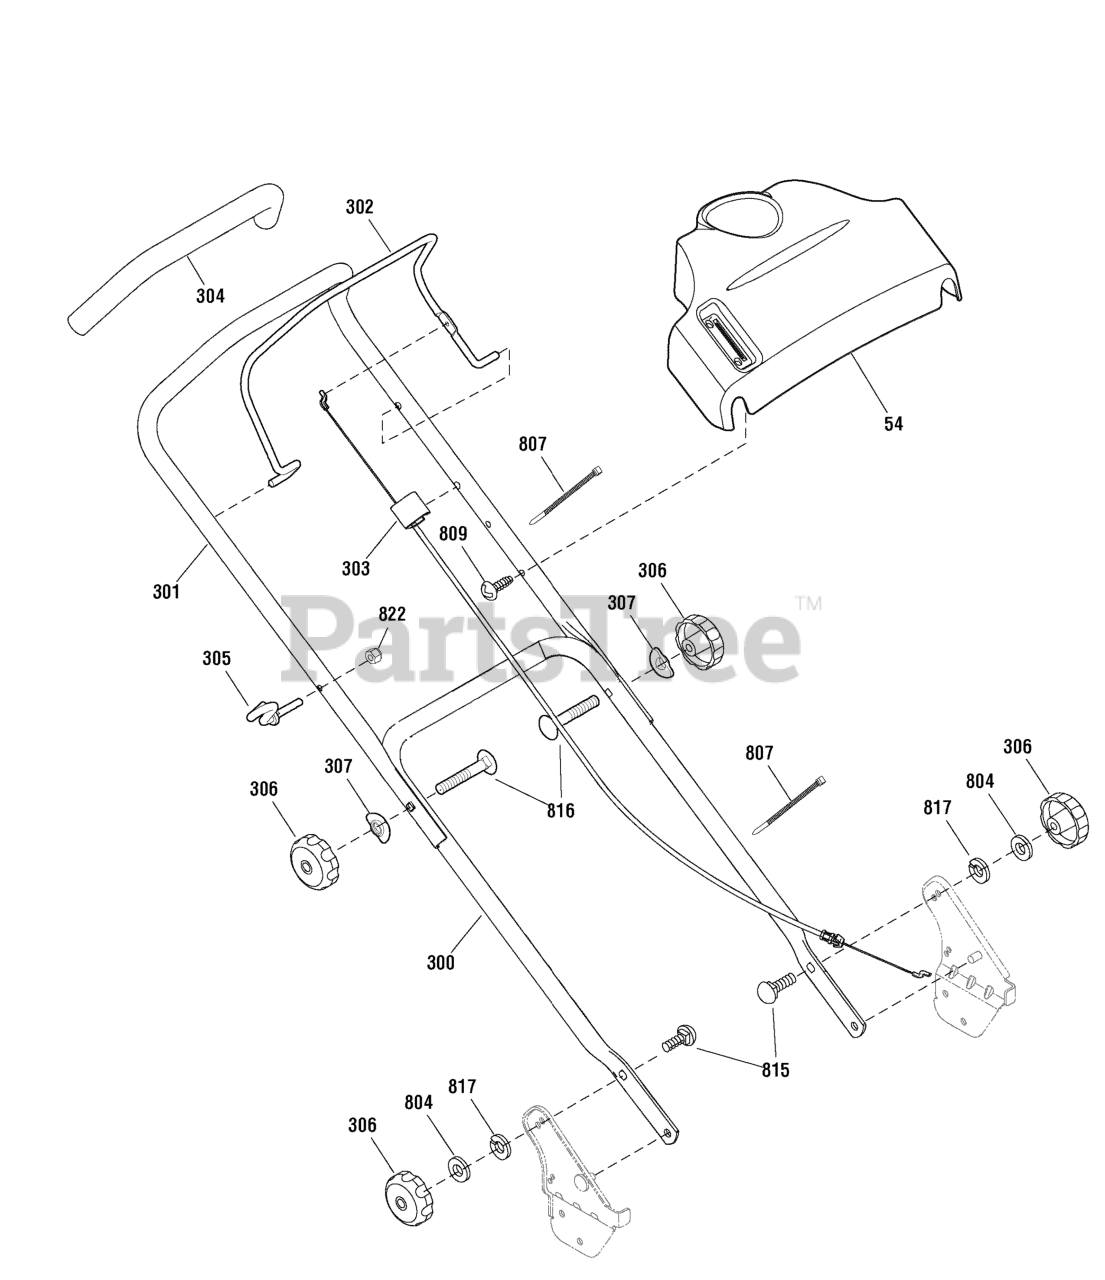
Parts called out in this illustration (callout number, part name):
54	CONTROL PANEL
300	HANDLE, Lower
301	HANDLE, Upper
302	LEVER, Engine Stop
303	CABLE, Engine Stop
304	TUBING, Foam
305	GUIDE, Rope
306	KNOB, Adjuster
307	WASHER, Formed
804	WASHER, 5/8
807	CABLE TIE
809	SCREW, Self Tap, #10-16 x 1/2
815	BOLT, Carriage, 5/16-18 x 1-1/8
816	BOLT, Carriage, 5/16-18 x 2
817	Washer, Lock
822	NUT, Hex, 1/4-20
